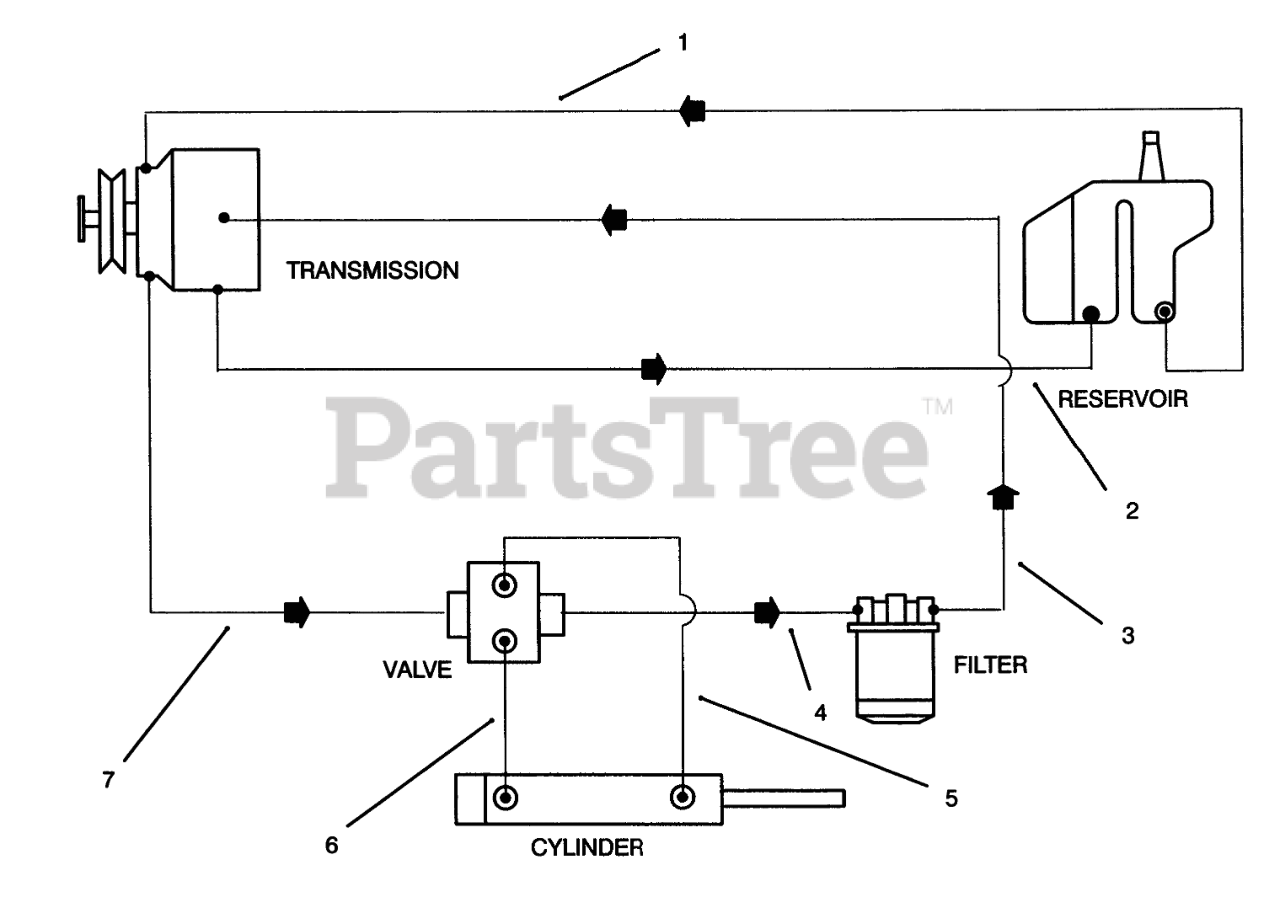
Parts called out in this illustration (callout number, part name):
1	HOSE ASM
2	TUBE ASM
3	HOSE ASM
4	HOSE ASM
5	HOSE ASM
6	HOSE ASM
7	HOSE ASM
